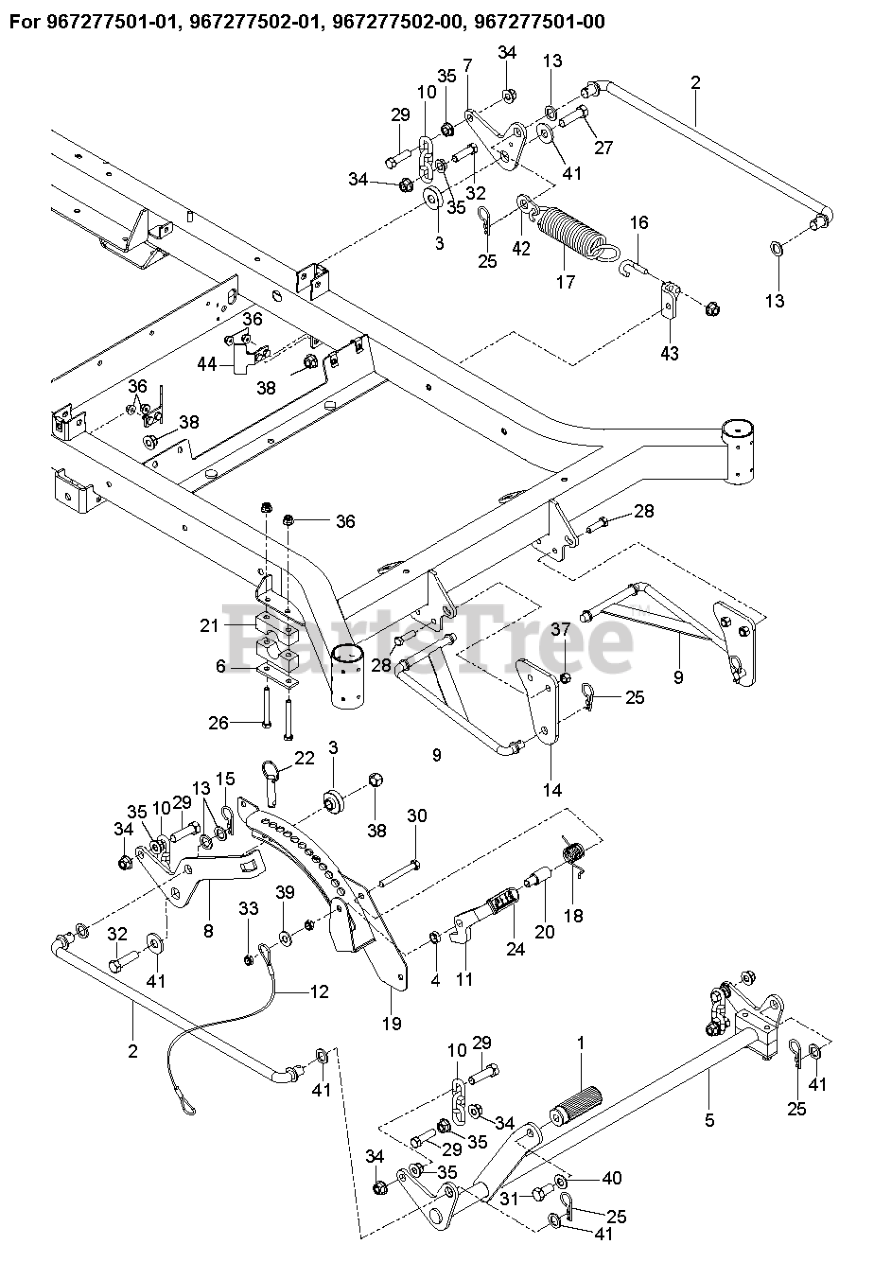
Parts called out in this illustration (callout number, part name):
1	PEDAL, DECK HEIGHT
2	CROSS LINK
3	IDLER SPACER
3	SPACER.IDLER.METAL.POWDER
4	SPACER, .3
5	LIFT.PNT.MZ.DECK.WELD.E-DIP
5	SHAFT FRONT LIFT BLK
6	REINFORCEMENT.PLATEX431
7	BELLCRANK, RR, LIFT
8	BELLCRANK REAR.RT BLACK X431
8	BELLCRANK, RR, RT
9	STRUT LINKAGE
10	LIFT CHAIN - 3 LINK
11	LATCH, TRANSPORT
13	WASHER LT
14	MOUNT, STRUT
15	PIN.COTTER.7/16.BOW TI.
18	SPRING, TORSION
19	HEIGHT, ADJUST, DECK
20	PIVOT, LATCH, TRANSPORT
21	PILLOW BLOCK
22	PIN, 1/2 X 1 1/2, DETENT RING
24	GRIP, TRANSPORT-RELEASE
25	PIN, COTTER 1 3/4
26	BOLT HEX
26	HCS 5/16C X 2-3/4
27	HCS 1/2-13 X 1 3/4 GR 8
28	HCS 3/8C X 1 1/4 GR5
29	HCS 7/16C X 1 1/2
30	HCS 3/8C X 3
30	BOLT.HEX.FIN.3/8-16 X 3.GR5
31	HHCS 1/2-13 X 1
32	HCS 7/16 - 14 X 1 3/4
33	NUT HEX 3/8-16 NYLON, THIN
34	NUT 7/16-14 HEX WHIZ LK
35	NUT 7/16C WHIZ
36	5/16-18 NYLOC FLANGE NUT
37	NUT 3/8-16 NYLOC
38	NUT.LK.W/WSH.1/2.
39	RP WASHER 3/8 FLAT
40	WASHER, 7/16 DISC SPRING
40	CONTACT BELLSPR 1/2
41	WASH USS FLAT 1/2
41	WASHER.9/16 X 1 3/8 X 12 GA.
42	TAB, SPRING
43	MOUNT, SPRING
44	STOP DECK. EZ+ BLACK - MS431
